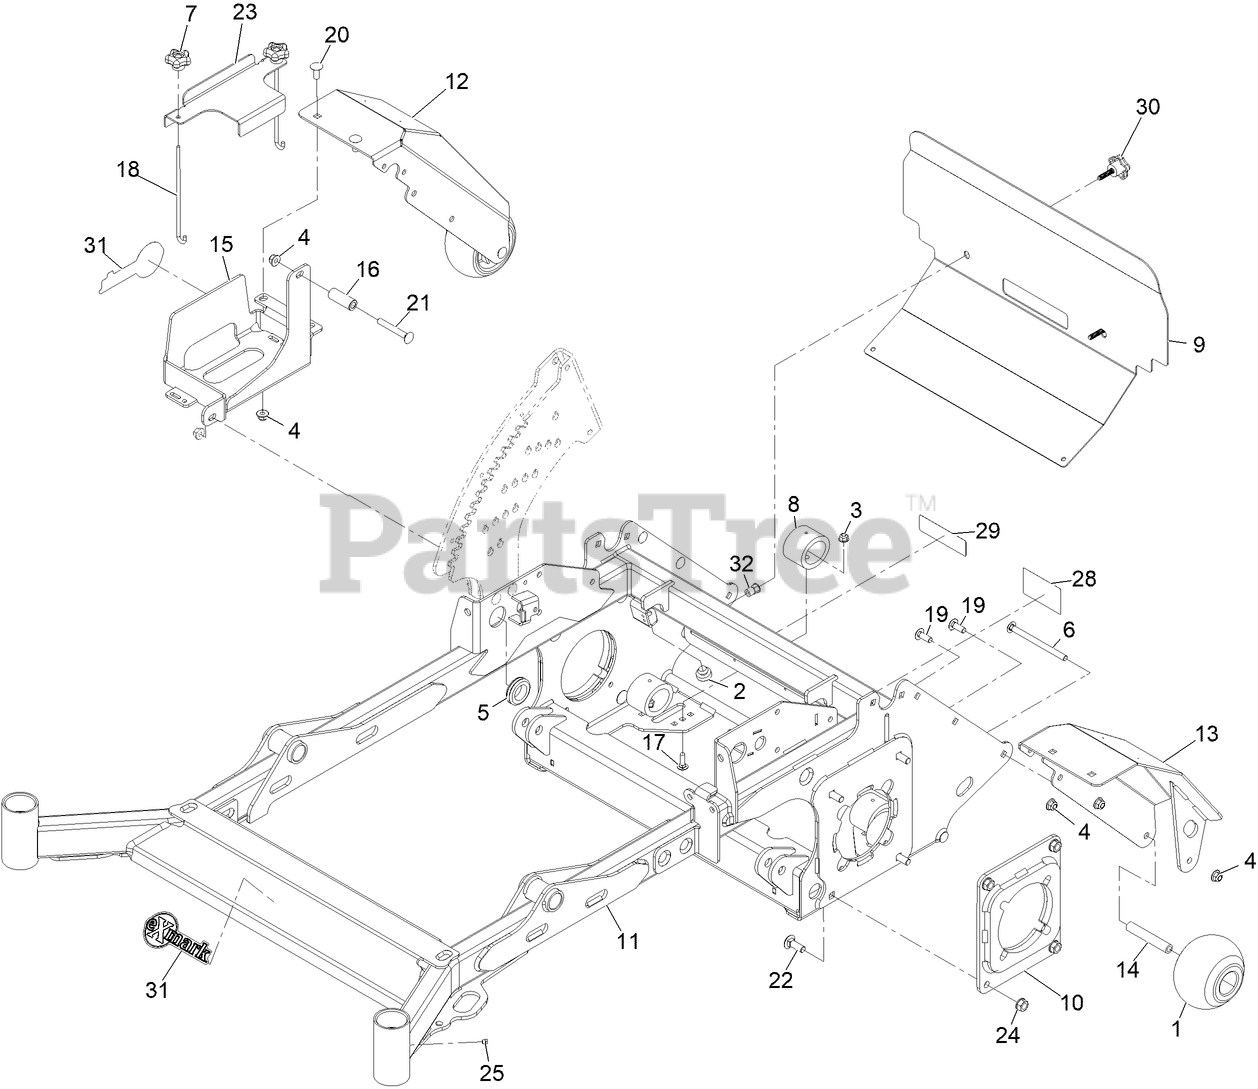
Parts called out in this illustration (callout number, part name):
1	ROLLER-SCALP, ANTI
2	BUMPER-RUBBER
3	NUT-HF, NI
4	NUT-HF, NI
5	GROMMET
6	BOLT-CARR
7	KNOB-HANDLE
8	BUMPER-ISOLATOR
9	GUARD-REAR FOOT
10	WLD-MTR MOUNT 48/52
11	MAINFRAME ASM - 48/52
12	Fender- Wheel RH [red]
13	Fender- Wheel LH [red]
14	SPACER- ROLLER
15	Tray-Battery Box
16	SPACER- ROLLER
17	BOLT-CARR
18	BOLT-HOLDDOWN
19	SCREW-CARR
20	SCREW-CARR
21	SCREW-CARR
22	BOLT-CARR
23	BRACKET-BATTERY HOLD DOWN
28	DECAL-DRIVE RELEASE
29	DECAL-COVER, MISSING
31	DECAL-EXMARK LOGO
32	NUT-CLINCH
